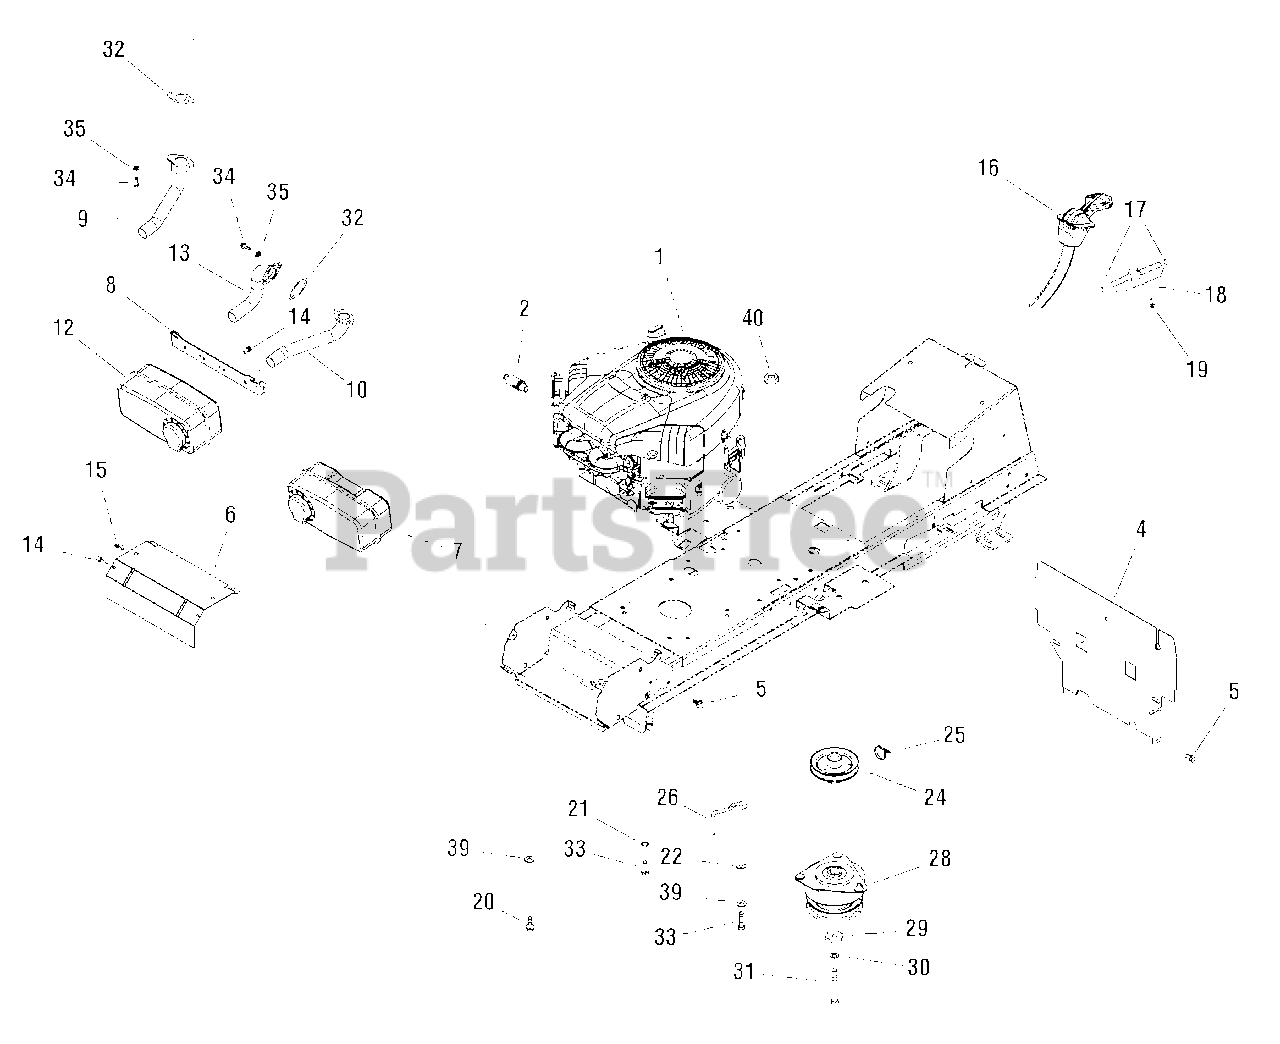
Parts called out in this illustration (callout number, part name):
1	* ENGINE, 19.5HP B&S Intek Single
1	* ENGINE, 22HP B&S Intek Twin
2	VALVE, Shut-off
4	HEAT SHIELD
5	SCREW, Taptite, 5/16-18 x 5/8
6	HEAT SHIELD
7	MUFFLER, B&S Twin
8	BRACKET, Muffler Mount
9	PIPE, Exhaust, LH Side
10	PIPE, Exhaust, RH Side
12	MUFFLER, B&S Single
13	PIPE, Exhaust
14	SCREW, Taptite, 1/4-20 x 1/2
15	CLIP, Wire
16	CONTROL, Throttle (20.5" & 23.5")
16	CONTROL, Throttle (34.75" & 36.5")
17	CLAMP, Hose UM5008
18	HOSE, Fuel 1-9920-247
19	CLIP, Hose
20	SCREW, Taptite, 3/8-16 x 1
21	WASHER, Lock, External Tooth, 3/8
22	WASHER, Flat. 3/8
24	PULLEY & HUB ASSEMBLY
26	ROD, Clutch Retainer, Long (BLK)
28	Clutch, Electric (LONG OGURA)
29	WASHER, Hex 1/2
30	LOCKWASHER, 7/16
31	CAPSCREW, Hex Head 7/16-20 x 3-1/2
32	GASKET, Exhaust
33	SCREW, Hex Head, 3/8-16 x 1-1/4
34	SCREW
35	LOCKWASHER
39	WASHER, 8.4
